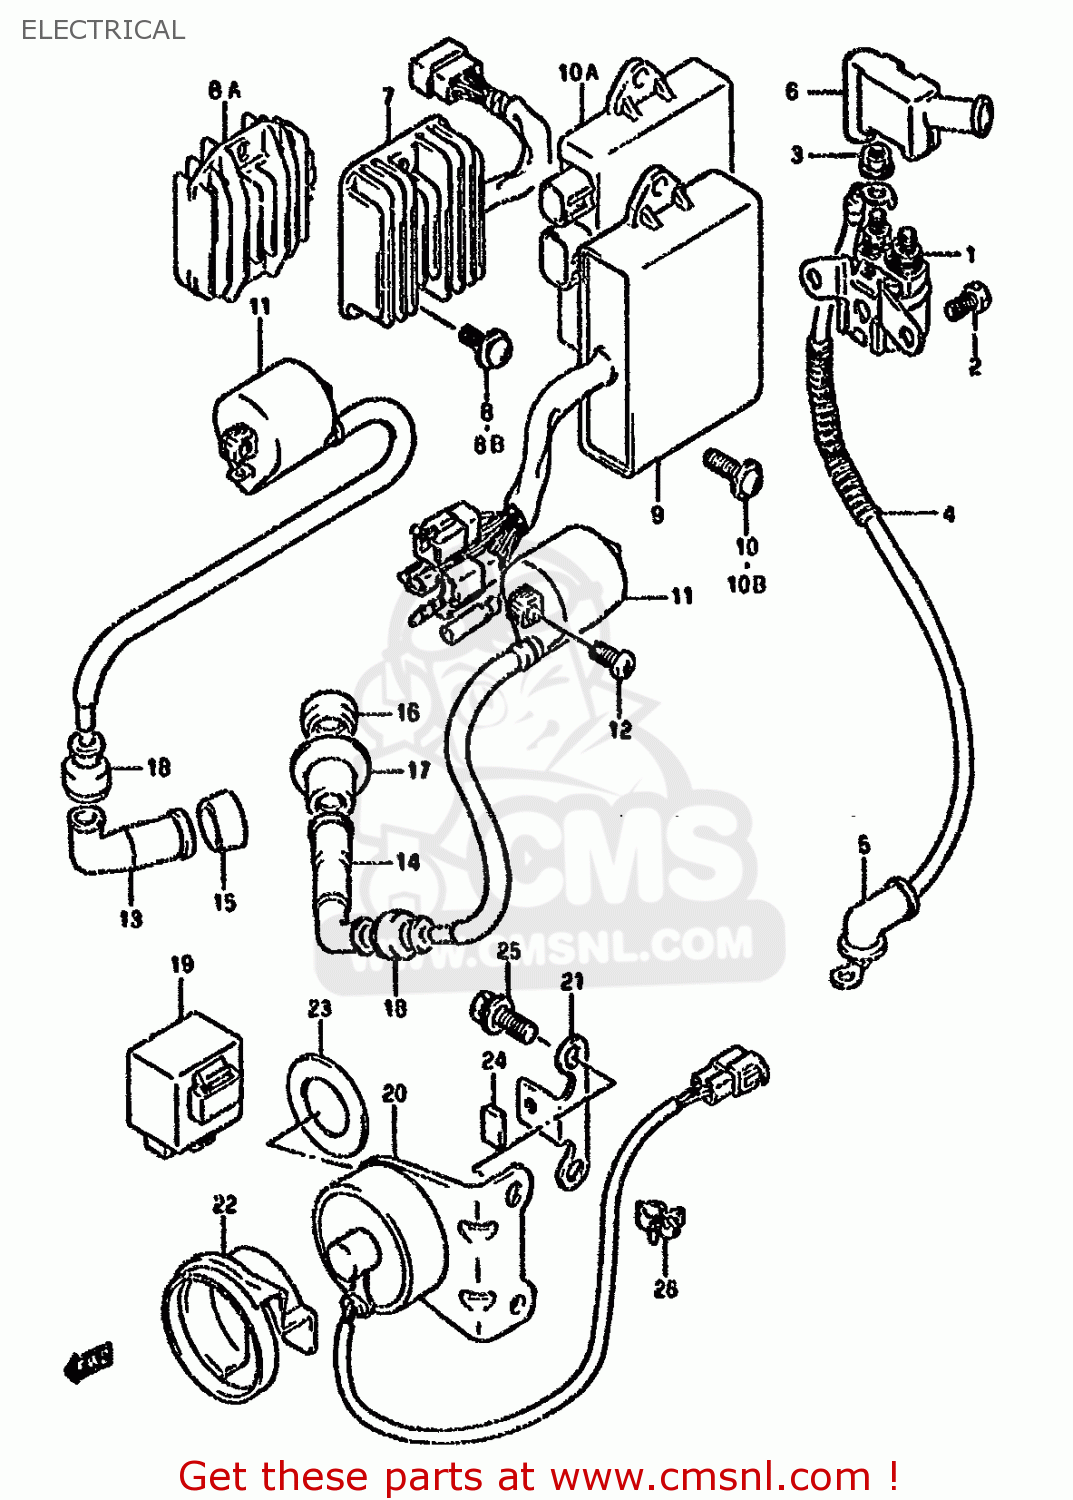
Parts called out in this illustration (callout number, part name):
1	RELAY ASSY,STARTING MOTOR
2	BOLT
3	NUT
4	WIRE,STARTER MOTOR LEAD
5	CAP,STARTER MOTOR LEAD
6	CAP, STARTER RELAY
7	RECTIFIER ASSY
8	SCREW
8A	RECTIFIER ASSY
8B	SCREW
9	UNIT,CDI
10	SCREW
10A	CDI UNIT
10B	SCREW
11	COIL ASSY,IGNITION
12	SCREW
13	CAP,SPARK PLUG
14	CAP,SPARK PLUG
15	SEAL,SPARK PLUG CAP
16	SEAL,SPARK PLUG
17	COVER,SPARK PLUG CAP,L
18	SEAL,HIGH TENSION CORD
19	CONTROL UNIT,DECOMP
20	SOLENOID ASSY,DECOMP
21	STOPPER,DECOMP
22	COVER DECOMP S
23	CUSHION,DECOMP
24	CUSHION,BATTERY(80X27X3)
25	BOLT
26	CLAMP
